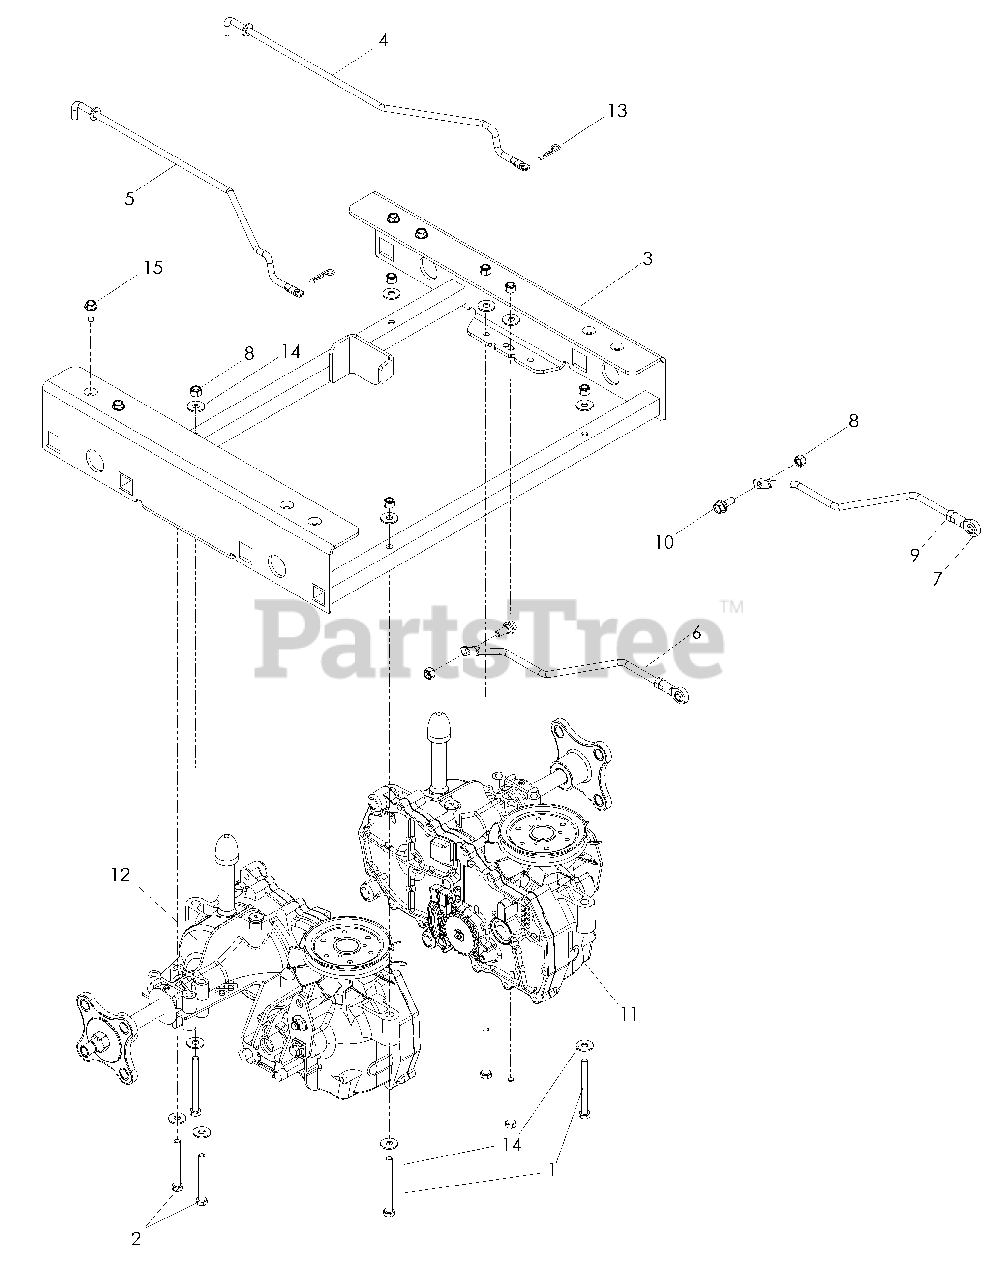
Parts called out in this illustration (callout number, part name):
1	HCS, 5/16-18 x 3 1/4
2	HCS, 5/16-18 x 2 3/4
3	SUB FRAME
4	BYPASS LINKAGE, LT
5	BYPASS LINKAGE, RIT
6	MOTION CNTRL ROD ASSM
7	END BALL, RT
8	NUT, 5/16-18, NYLOC
9	NUT, 5/16-24
10	BOLT, SHOULDER, 5/16
13	PIN HAIR, .073 x 17/16
14	WASHER, 5/16
15	SCREW, 5/16-18 x 1 THD CUT
